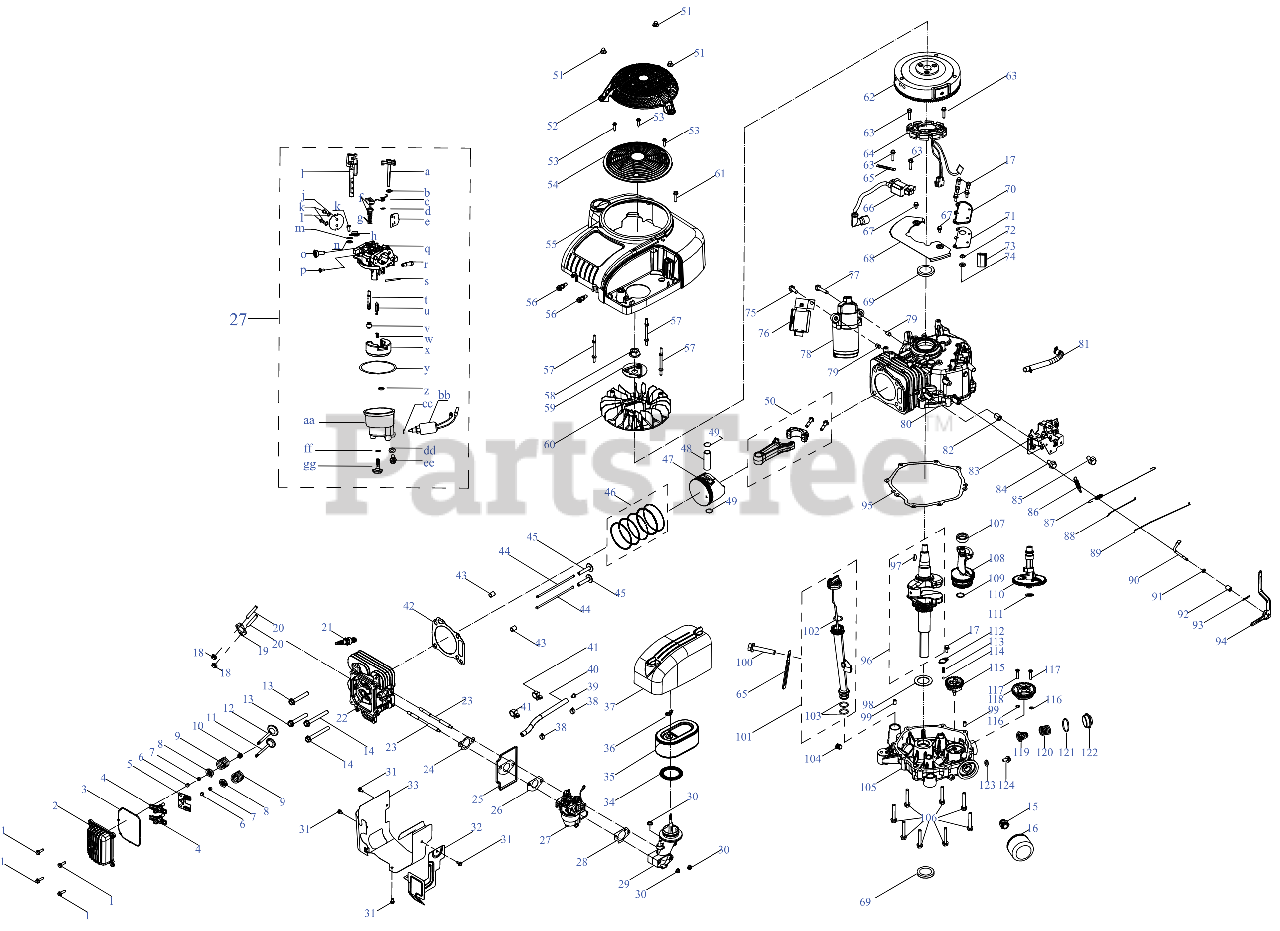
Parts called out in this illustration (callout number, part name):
1	BOLT M6 x 22
2	VALVE COVER
3	VALVE COVER RINGER GASKET
4	ROCKER ARM ASSEMBLY
5	PUSH ROD GUIDE
6	EXHAUST VALVE ADJUSTER
7	VALVE CAP
8	VALVE SPRING SEAT
9	VALVE SPRING
10	INTAKE VALVE SEAL
11	EXHAUST VALVE
12	INTAKE VALVE
13	SCREW M10-1.25 x 65 x GR10.9
14	SCREW M10-1.25 x 87 x GR10.9
15	SCREW JOINT OIL FILTER ADAPTER
16	ENGINE OIL FILTER
16	Cub Cadet OIL FILTER
16	Genuine Factory Parts OIL FILTER
17	BOLT M6-1 x 14 GR8.8
18	NUT M8
19	EXHAUST PIPE MUFFLER GASKET
20	MUFFLER STUD M8 x 47
21	SPARK PLUG
22	Cylinder Head
23	CARBURETOR STUD
24	CARBURETOR INSULATER GASKET
25	CARBURETOR INSULATOR
26	CARBURETOR GASKET
27	CARBURETOR ASSEMBLY - HY-8P92
28	MANIFOLD GASKET-ADD AIR HOLE
29	INTAKE MANIFOLD
30	HEX NUT
31	BOLT M5-.8 x 10
32	CARBURETOR SHIELD BRACKET
33	COWL SHIELD
35	AIR FILTER
35	Genuine Factory Parts AIR FILTER
36	WING NUT
37	AIR FILTER COVER ASSEMBLY
38	HOSE CLAMP
40	FUEL HOSE 6.3X12X290
41	FUEL LINE SUPPORT CLAMP
42	CYLINDER HEAD GASKET
43	DOWEL PIN
44	PUSH ROD
45	TAPPET
46	PISTON RING SET
47	PISTON
48	PISTON PIN
49	PISTON PIN SNAP RING
50	CONNECTING ROD ASSEMBLY
51	ACORN NUT
52	BLOWER HOUSING SCREEN
53	BOLT 5.5 x 25
54	DEBRIS SHIELD
55	ENGINE SHROUD
56	HOOK BOLT
57	STARTER/SHROUD STUD M6 x 100
58	FLYWHEEL NUT M16X1.5
59	FAN MOUNTING PLATE
60	COOLING FAN
61	BOLT M6 x 16
62	FLYWHEEL
63	BOLT-M6-1 x 28 GR8.8
64	CHARGING COIL
65	FLEXIBLE CLAMP
66	IGNITION COIL ASSEMBLY
67	BOLT M6-1 x 10 GR8.8
68	COWL COVER SHIELD
69	OIL SEAL
70	BREATHER COVER PLATE
71	BREATHER GASKET
72	BREATHER VALVE
73	MESH SCREEN FILTER
74	BREATHER VALVE BASE
75	BOLT M8 x 40
76	REGULATOR ASSEMBLY
77	STUD - M8-6 x 58
78	STARTER ASSEMBLY
79	DOWEL PIN
80	CRANKCASE
81	BREATHER HOSE ASSEMBLY
82	COMPONENT BRACKET SPACER
83	COMBINATION CONTROL BRACKET ZS
84	BOLT M6 x 38
85	BOLT M6-1 x 18 GR8.8
86	GOVERNOR SPRING
87	THROTTLE LINKAGE SPRING
88	CHOKE LINKAGE ROD
89	THROTTLE LINKAGE ROD
90	GOVERNOR ARM SHAFT
91	GOVERNOR WASHER
92	GOVERNOR SEAL
93	COTTER PIN
94	GOVERNOR ARM
95	CRANKCASE COVER GASKET
96	CRANKSHAFT ASSEMBLY
97	FLYWHEEL KEY
98	CRANKSHAFT THRUST WASHER
99	DOWEL PIN
100	HHFLG M6-1 x 35 CL8.8
101	DIPSTICK ASSEMBLY
102	OIL FILL TUBE ASSEMBLY
103	O-RING
104	ENGINE PLUG 3/8 NPT
105	CRANKCASE COVER
106	BOLT M8 x 54
107	BALL BEARING
108	BALANCE GEAR SHAFT ASSEMBLY
109	BALANCEABLE THRUST
110	CAMSHAFT ASSEMBLY
111	CAMSHAFT THRUST WASHER
112	PRESSURE RELEASE COVER
113	PRESSURE RELEASE SPRING
114	OIL PUMP STEEL BALL
115	GOVERNOR GEAR/SHAFT ASSEMBLY
116	O-RING
118	OIL PUMP ASSEMBLY
119	SUMP FILTER
120	FILTER SPRING
121	O-RING
122	FILTER COVER
123	OIL DRAIN PLUG WASHER
124	BOLT M8 x 15
